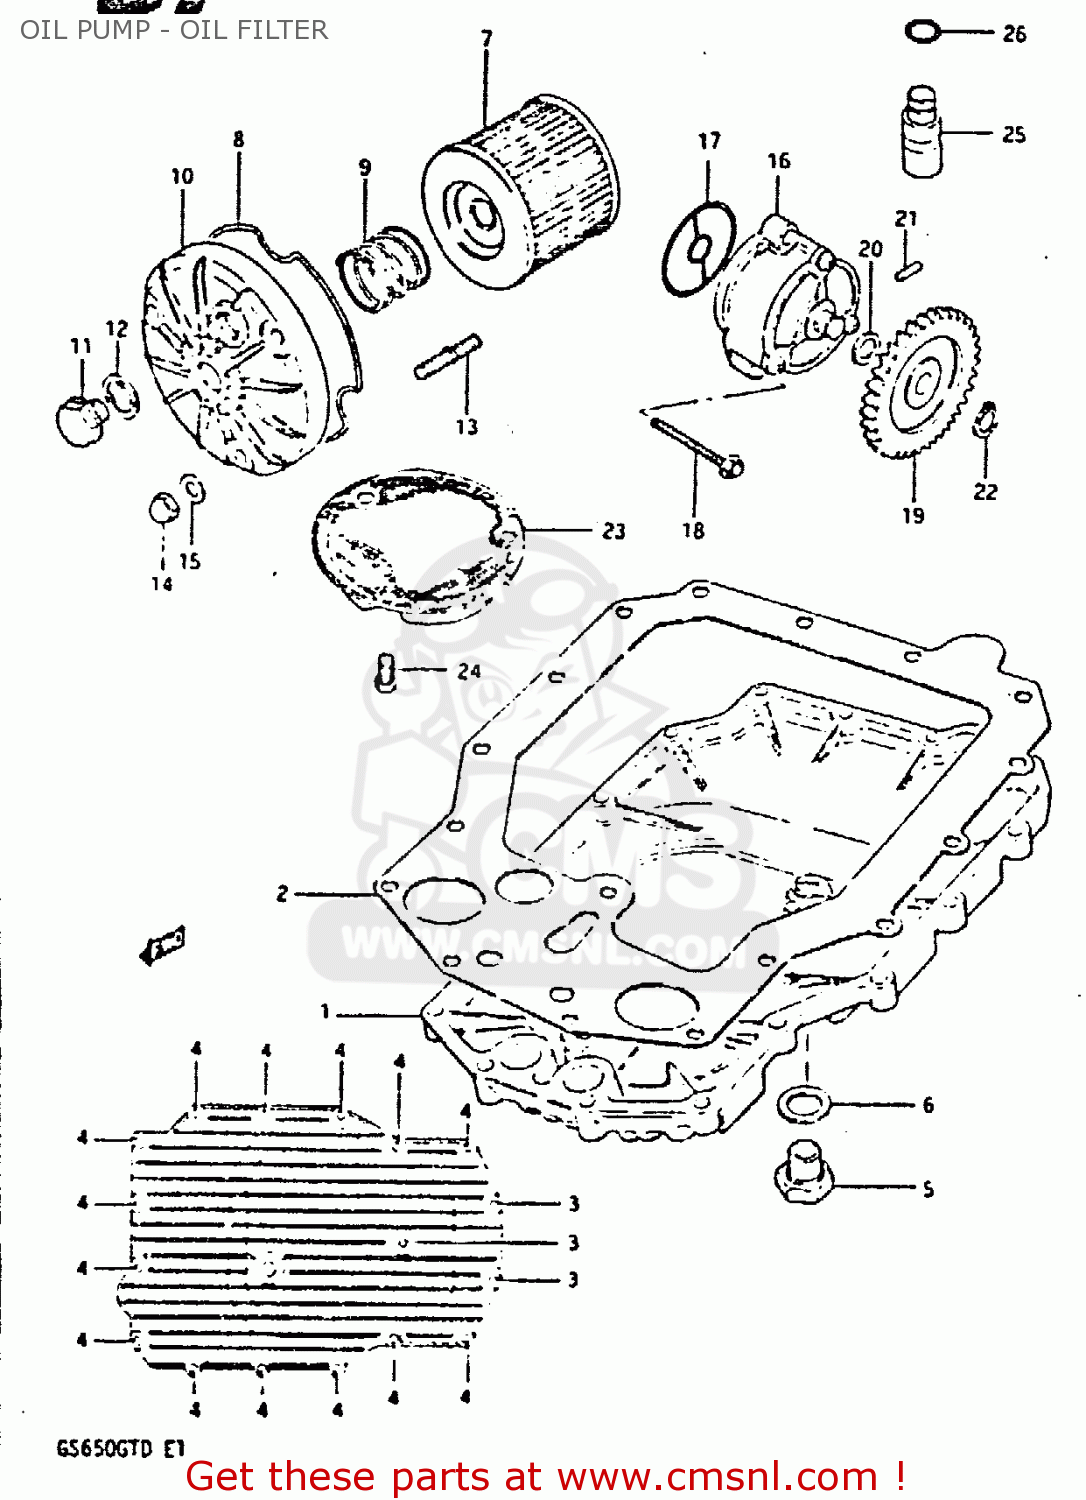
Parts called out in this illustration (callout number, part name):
1	PAN,OIL
2	GASKET,OIL PAN (MCA)
3	BOLT 6X30
4	BOLT
5	PLUG
6	GASKET(14X19.2X2) (NAS)
7	FILTER ASSY,ENGINE OIL
8	O RING,OIL FILTER CHAMBER CAP
9	SPRING
10	CAP,OIL FILTER
11	PLUG (14X12)
12	GASKET(14X19.2X2) (NAS)
13	STUD 6X20
14	NUT 6MM
15	WASHER
16	PUMP ASSEMBLY,ENGINE OIL
17	O-RING,OIL PUMP
18	BOLT
19	GEAR,ENG OIL PUMP DRIVEN(NT:33
20	SHIM
21	PIN(4X15.8)
22	CIRCLIP
23	STRAINER,ENGINE OIL
24	SCREW 6X12
25	REGULATOR ASSEMBLY,ENGINE
26	O-RING
